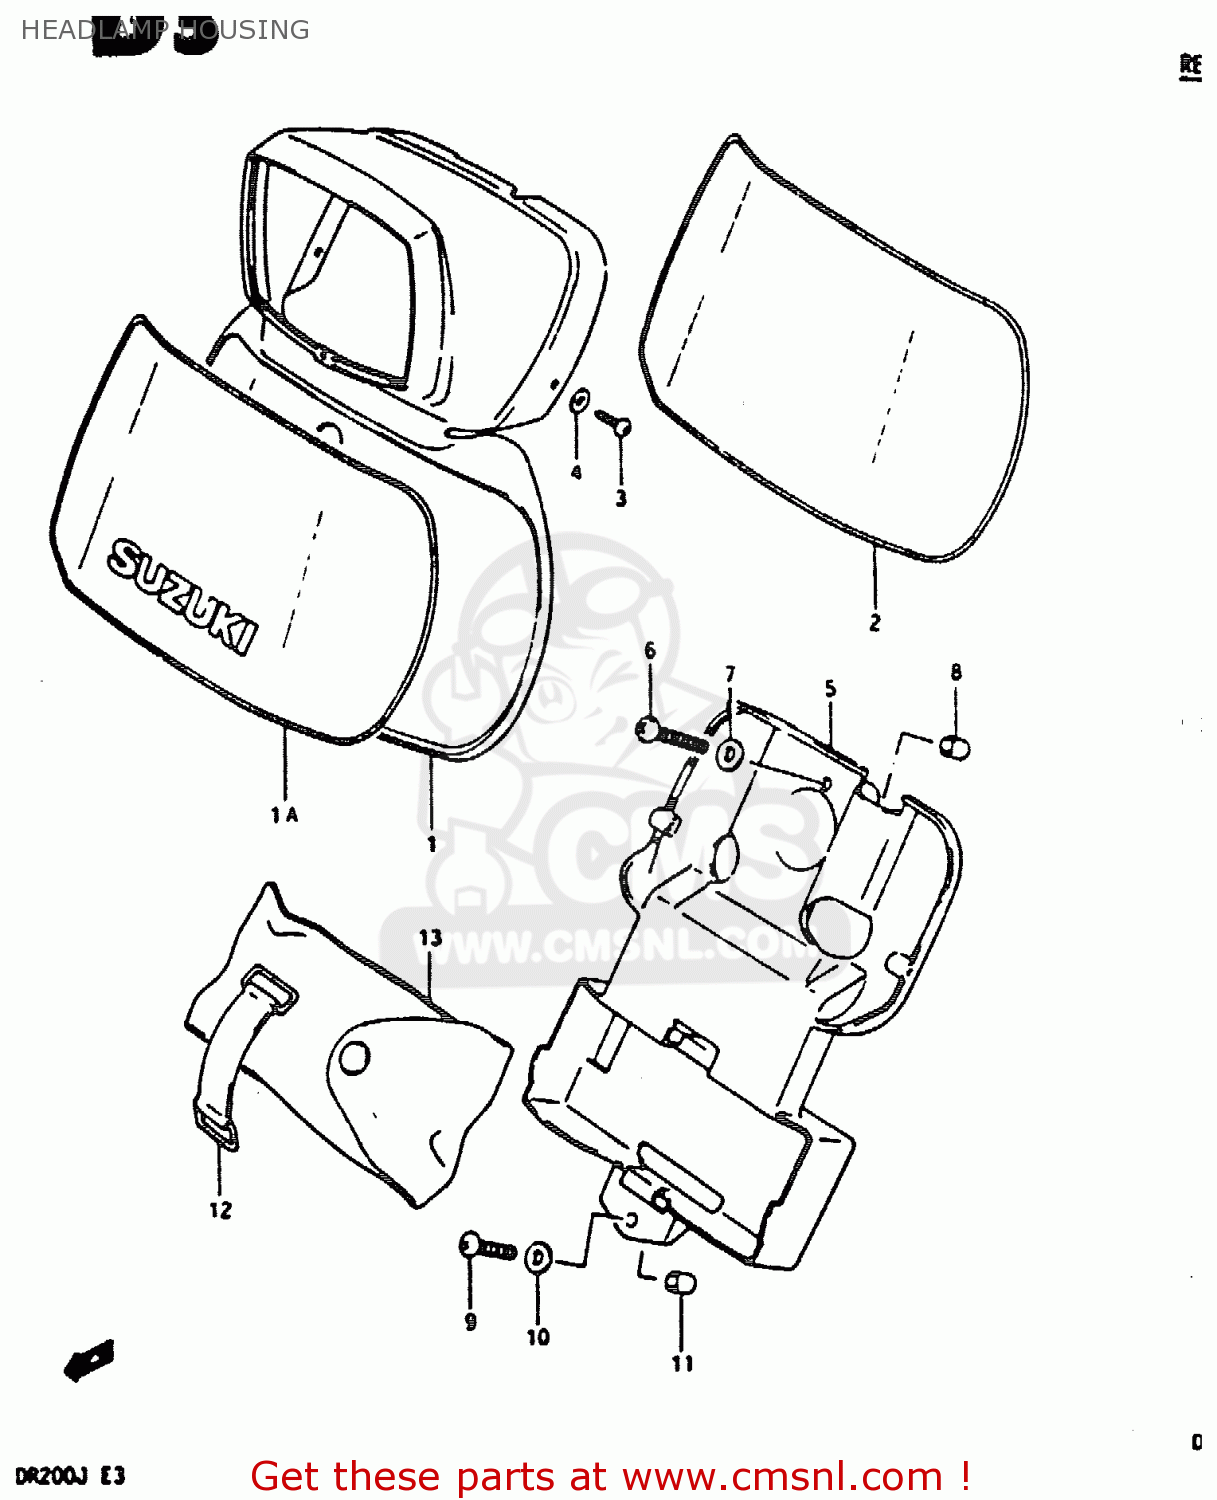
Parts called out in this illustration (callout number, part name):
1	HOUSING,HEADLAMP
1A	TAPE SET,HEADLAMP COVER
2	TAPE SET
3	TAPPING SCREW
4	WASHER 4MM
5	HOLDER,TOOL
6	SCREW
7	WASHER
8	SPACER (6.8X10X27.4)
9	SCREW
10	WASHER
11	SPACER (6.8X10X10)
12	BAND
13	TOOL SET
